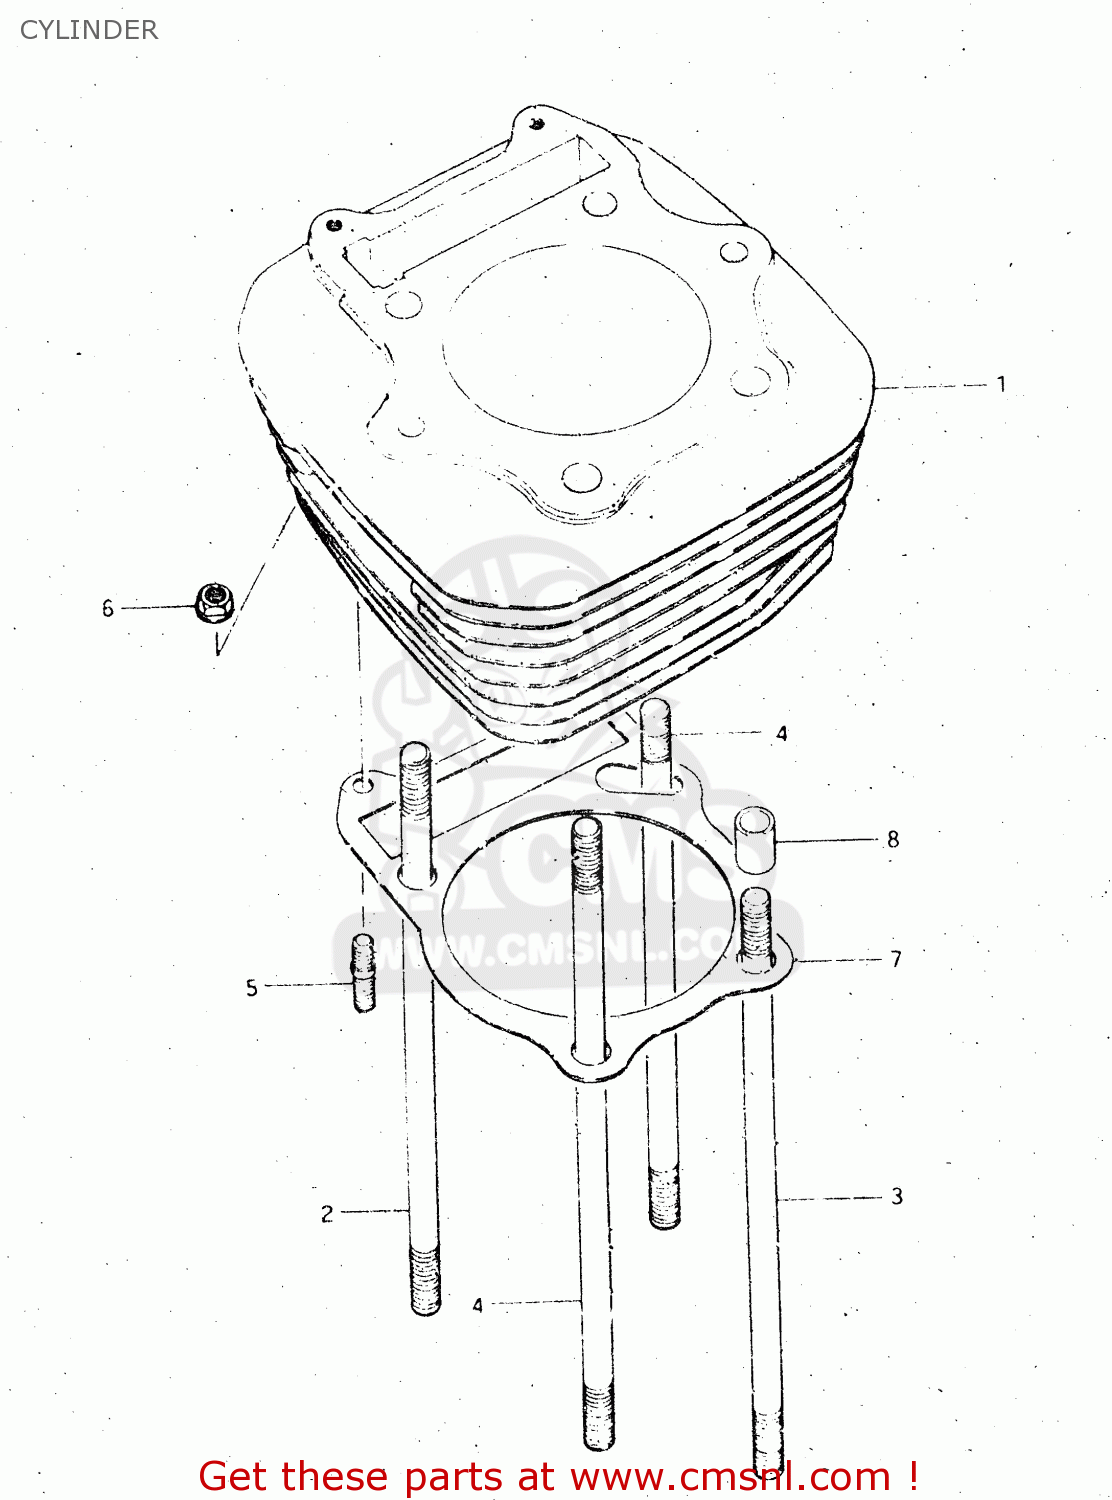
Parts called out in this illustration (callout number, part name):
1	CYLINDER
2	STUD
3	STUD
4	BOLT,STUD
5	STUD 6X25
6	NUT
7	GASKET,CYLINDER (NAS)
8	PIN
